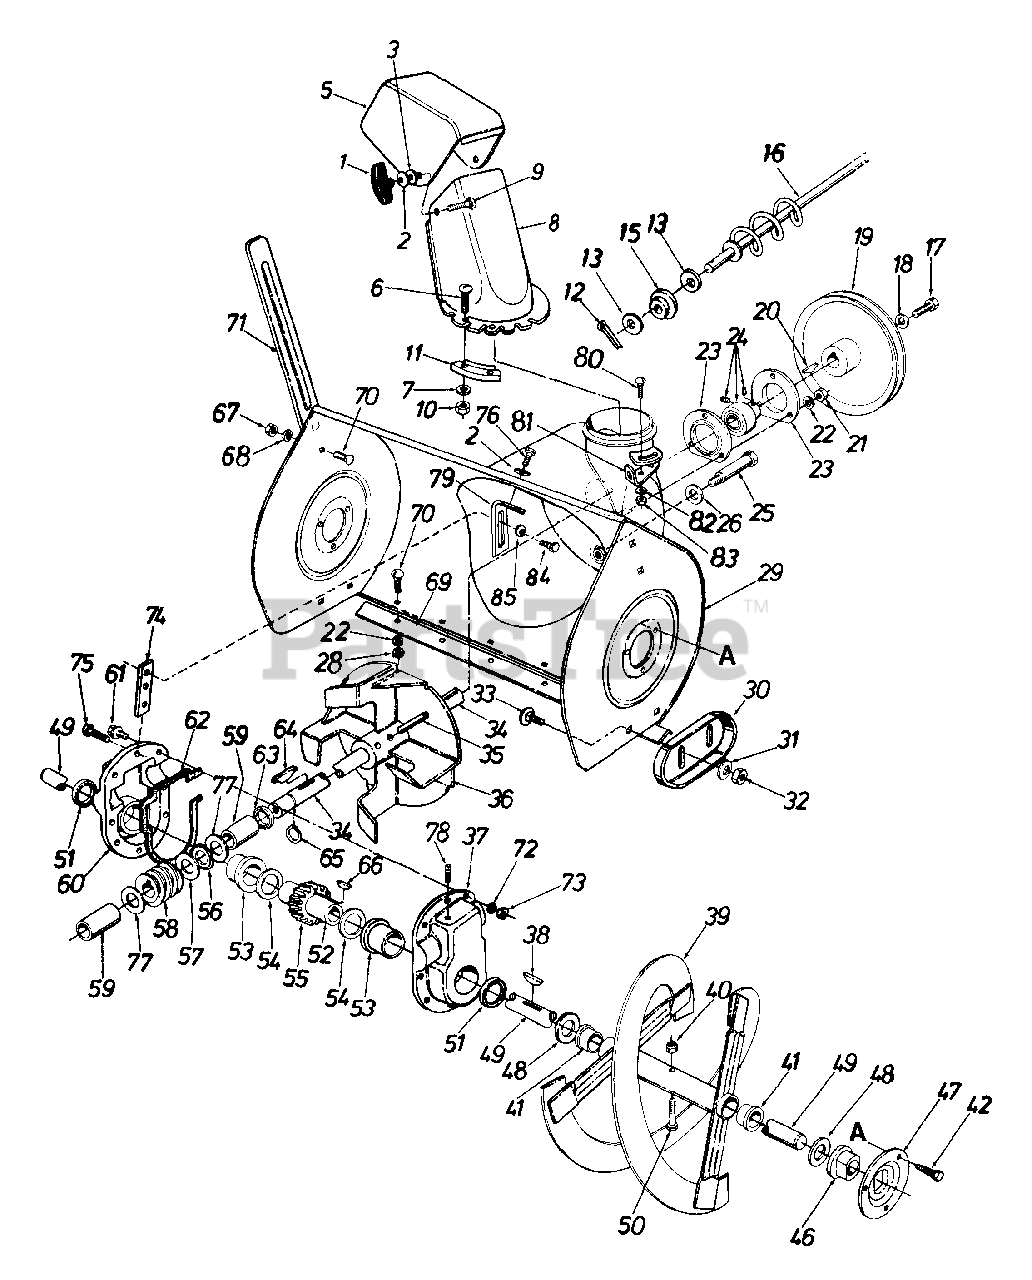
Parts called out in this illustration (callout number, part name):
1	Hand Knob Ass'y,
2	Bell-Wash..345 I.D. x.88 O.D. x .060
3	Fl. Wash..312 I.D. x 1.125 O.D. x .125
5	Top Chute
6	Truss Mach. Scr. 1/4-20 x. 75"
7	Fl-Wash. 1/4" I.D.
8	Chute
9	Carr. Bolt 5/16-18 x 1.00" Lg.
10	Hex Cent. L-Nut 1/4-20 Thd.
11	Chute Flange Keeper
12	Cotter Pin
13	Fl-Wash..385" I.D. x .62"
15	Bushing
16	Chute Crank Ass'y.
17	Hex L-Scr. 5/16-18 x .88" Lg.
18	Bell-Wash..345 I.D. x.88
19	V-Pulley .875 I.D. x 10.12
20	09 Hi-Pro Key 3/16 x 3/4" Dia.
21	Hex Nut 5/16-18 Thd.
22	L-Wash. 5/16" I.D.
23	Bearing Hsg. - Self Aligning Brg.
24	Self Aligning Brg..875 I.D.
25	Stud 3/8-16 x 2.75" Lg.
26	Bell-Wash..4001.0. x.88 O.D. x .060
28	Hex Nut 5/16-18 Thd.
29	Blower Hsg. Ass'y.
30	Slide Shoe
31	Bell-Wash..400 I D. x .88 O.D. x .060
32	Hex Jam Nut 3/8-16 Thd.
33	Carr. Bolt 3/8-16 x .62" Lg.
34	Blower Axle
35	Spring Pin Spiral 5/16" Dia. x 1.75" Lg.
38	#91 Woodruff Key 1/4" x 3/4" Dia.
39	Spiral Ass'y.- L.H.
40	Hex Ins. L-Nut 5/16-18 Thd.
41	Plastic Bushing
42	Hex Wash. Hd. Self-Tap Scr. 5/16-24 x .62" Lg.
46	Flange Brg. w/Flats 1.0" I.D.
47	Bearing Hsg.-Spiral Hsg.
48	Fl-Wash. 1.06 I.D. x 1.75" O.D x .100
49	Spiral Axle
50	Hex Bolt 5/16-18 x 1.75" Lg.
51	Oil Seal 1.50" I. D
52	Worm Gear Shaft
53	Flange Brg 1.503 I.D.
54	Fl-Wash..88 I.D. x 1.40 O.D.
55	Double Threaded Worm Gear
56	Thrust Brg..88 I.D. x 1.44 O.D. x .078
57	Fl-Wash..88 I.D. x 1.40 O.D.
58	Double Threaded Worm - L.H.
59	Sleeve Brg. 875" I.D.
60	Complete Gear Hsg. Half- R.H.
61	Hex Bolt 5/16-18 x 1.0 Lg.
62	Gasket
63	Oil Seal .875" I.D.
64	#9 Hi-Pro Key 3/16 x 3/4" Dia.
65	Snap Ring-.875 I.D.
66	091 Woodruff Key 1/4 x 3/4" Dia.
67	Hex Nut 5/16" I.D.
68	L-Wash. 5/16" I.D.
70	Carr. Bolt 5/16-18 x .62" Lg.
72	Wave Wash 5/16" I.D.
73	Hex Ins. L-Nut 5/16-18 Thd.
74	Gear Hsg. Support Plate
75	Hex Bolt 5/16-18 x .75" Lg.
76	Hex Wash. Hd. Self-Tap Scr. 5/16-18 x 75" Lg.
77	Fl-Wash 88 I.D. x 1.40 O.D.
78	Filler Plug
80	Carr. Bolt 5/16-18 x .75" Lg.
82	Bell-Wash..345 I.D. x 88"
83	Hex Nut 5/16-18 Thd.
84	Hex Bolt 1/4-28" I.D. x .75" Lg.
85	Bell-Wash..28" I.D. x.75" O.D.
